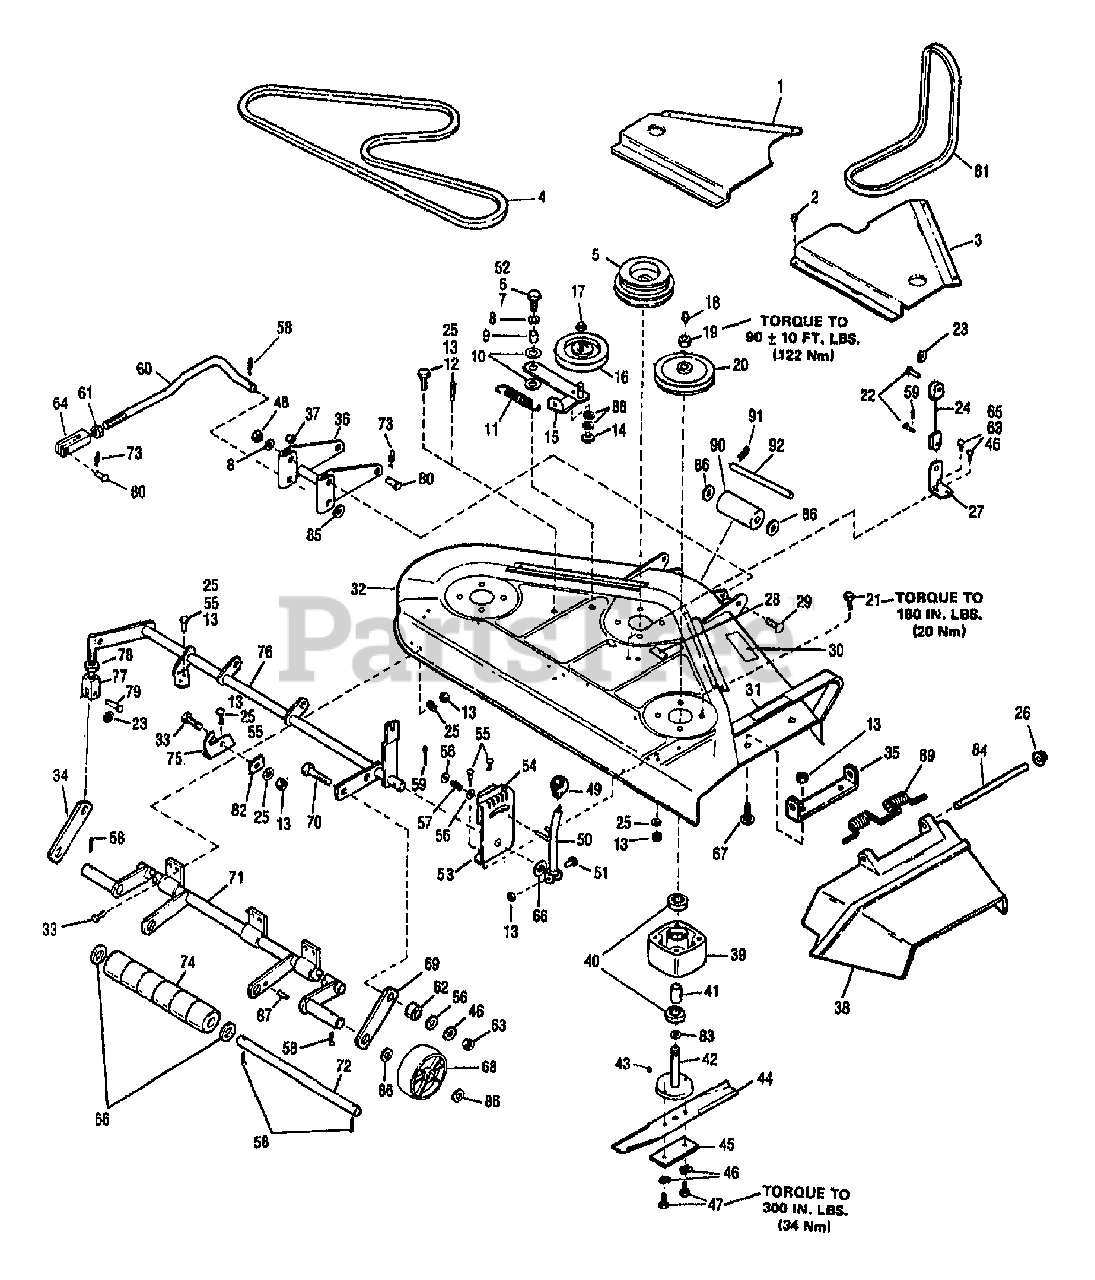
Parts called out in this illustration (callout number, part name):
8	WASHER-FLAT
32	BASE ASSY.
38	DEFLECTOR
55	CARRIAGE BOLT
